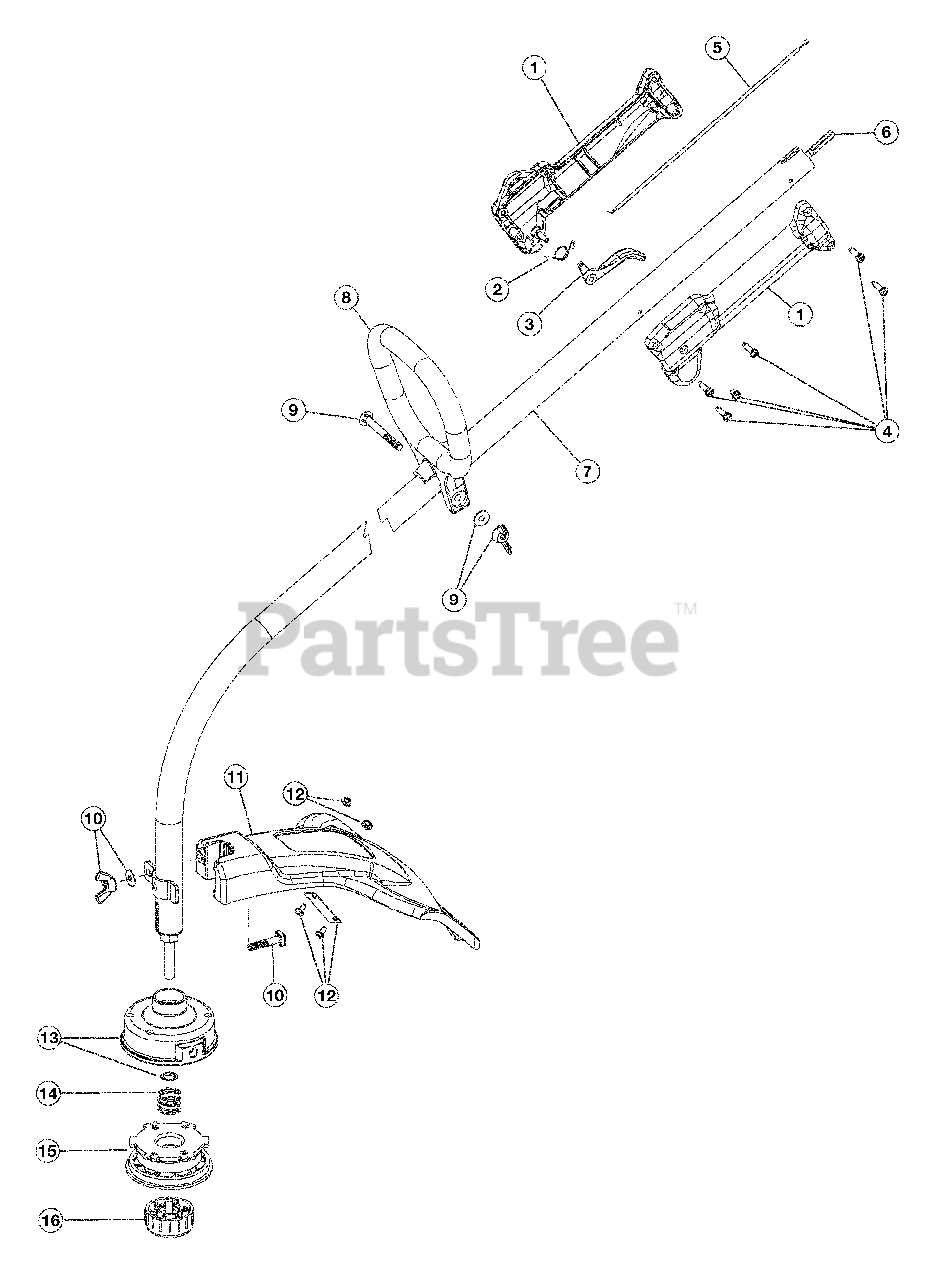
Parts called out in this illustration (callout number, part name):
1	Throttle Housing and Trigger Assembly
2	Throttle Trigger Spring
3	Throttle Trigger
4	Throttle Housing Screws
5	Throttle Cable
6	Flexible Drive Shaft
7	Drive Shaft Housing Assembly
8	D-Handle Assembly
9	D-Handle Hardware
10	Guard Mounting Hardware
12	Blade Assembly
13	Outer Reel w/Retainer
15	Inner Reel
16	Bump Knob
